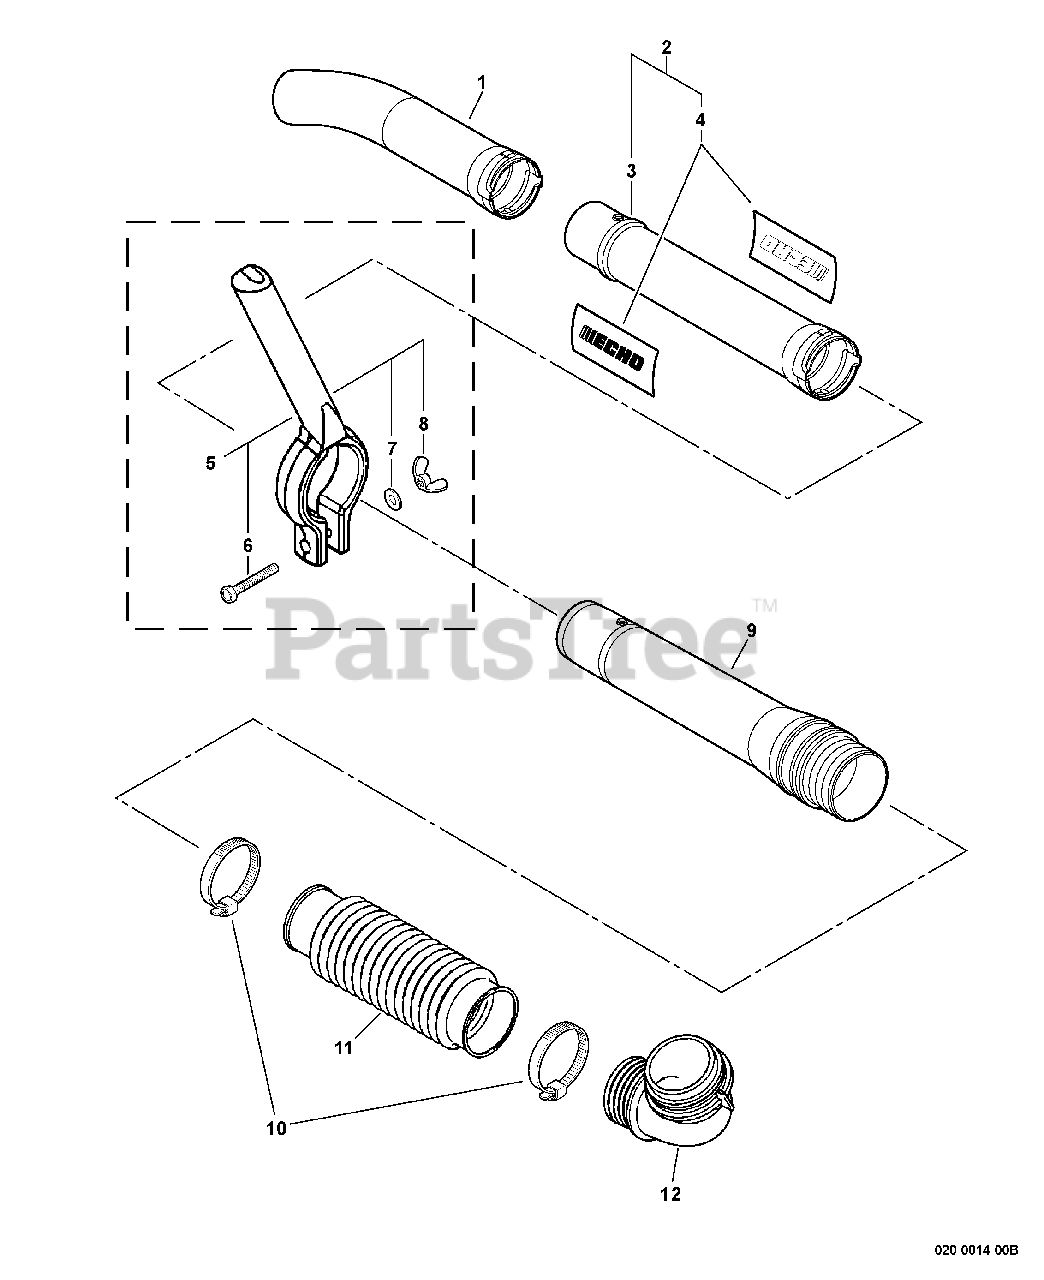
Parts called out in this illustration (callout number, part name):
1	TUBE, BLOWER - CURVED
2	BLOWER TUBE KIT - STRAIGHT
3	TUBE, BLOWER - STRAIGHT
4	LABEL - ECHO
5	HANDLE ASSY
6	BOLT - 6X45
7	WASHER - 6
8	WINGNUT - 6
9	TUBE, BLOWER - SWIVEL
10	CLAMP, HOSE
11	TUBE, BLOWER - FLEXIBLE
12	TUBE, BLOWER - ELBOW
